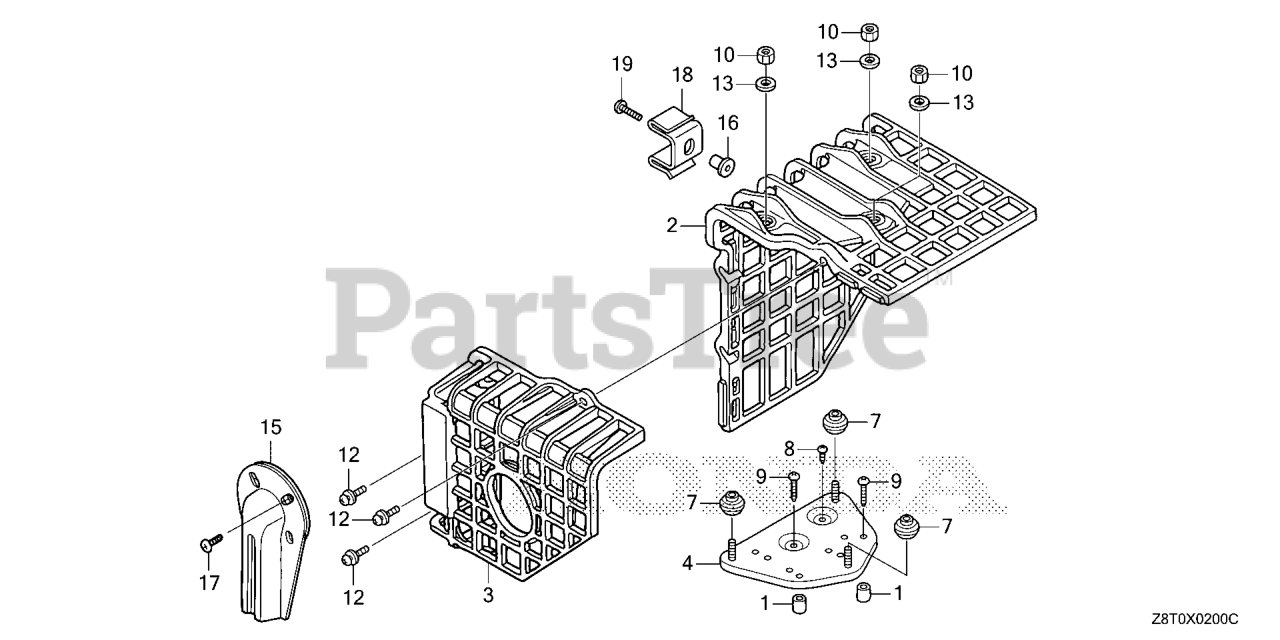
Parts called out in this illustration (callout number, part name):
1	COLLAR, AIR CLEANER HOUSING
2	COVER, MUFFLER
3	COVER, RR. MUFFLER
4	BASE, MUFFLER COVER
7	SPACER, MUFFLER COVER
8	SCREW, TAPPING (5X8)
9	SCREW, TAPPING (5X25)
10	NUT, HEX. (5MM)
12	SCREW-WASHER (6X20)
13	WASHER, PLAIN (5MM)
16	COLLAR, FAN COVER (Honda Code 5580527). (N/A: SEE ASSEMBLY)
18	STAY, MUFFLER COVER
19	SCREW, TAPPING (6X25)
